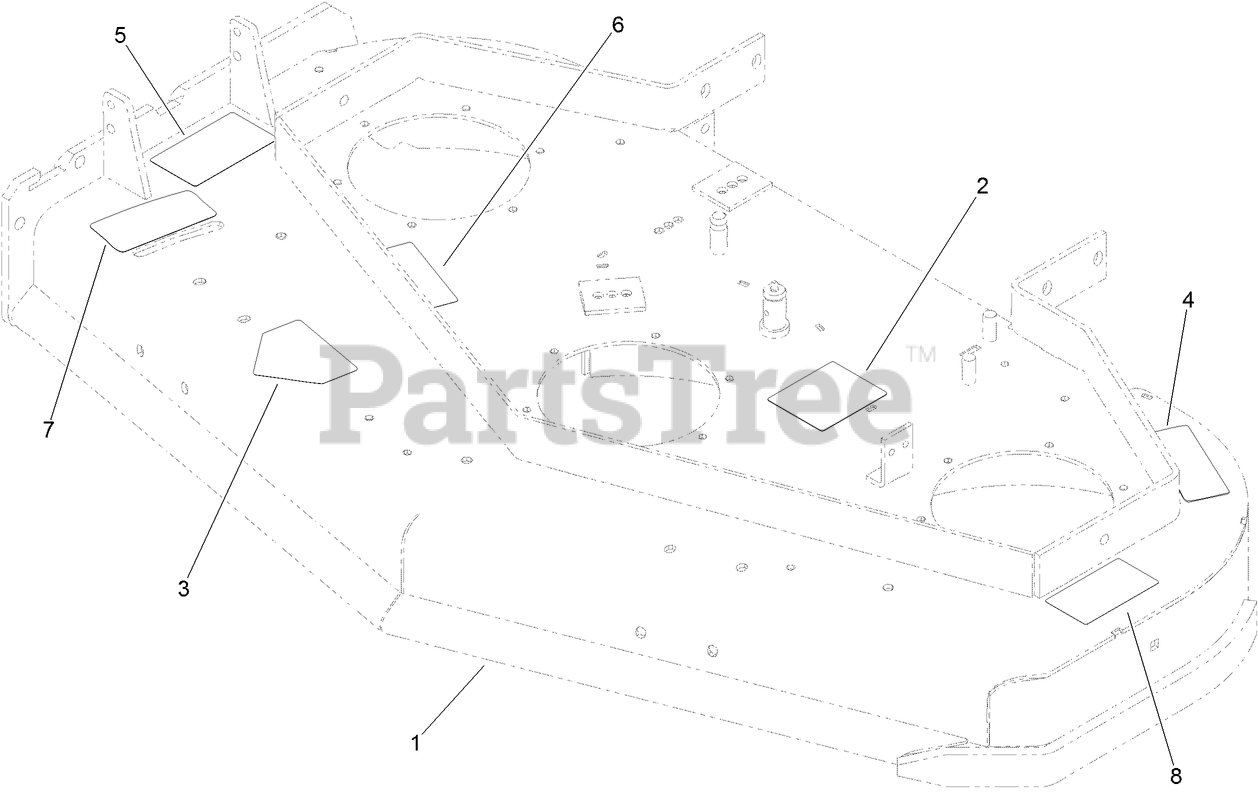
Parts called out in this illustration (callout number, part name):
1	48 INCH DECK ASM
2	DECAL-ROUTING, BELT
3	DECAL-DANGER
4	DECAL-TORQUE, BOLT
5	DECAL-DANGER
6	DECAL-MISSING, COVER
7	DECAL-ADJUSTMENT, BAFFLE
8	DECAL-DANGER
